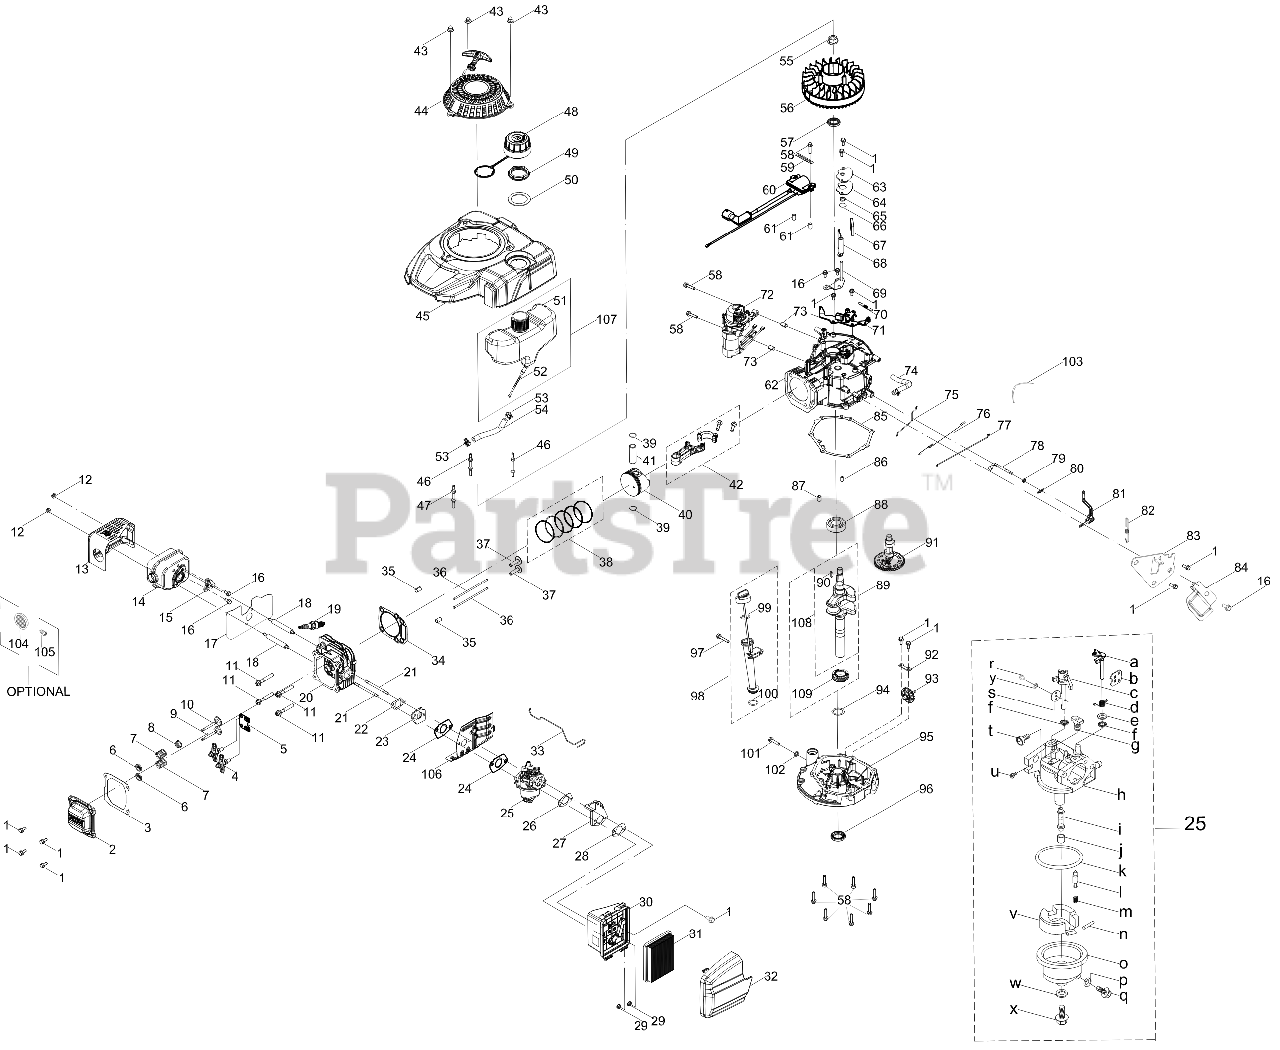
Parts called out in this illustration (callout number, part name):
1	BOLT M6-1 x 14 GR8.8
2	VALVE COVER
3	VALVE COVER GASKET
4	ROCKER ARM ASSEMBLY
5	PUSH ROD GUIDE
6	INTAKE VALVE SPRING RETAINER
7	VALVE SPRING
8	INTAKE VALVE SEAL
9	EXHAUST VALVE
10	INTAKE VALVE
11	SCREW M8 x 54 GR10
12	HEX NUT
13	MUFFLER SHIELD
14	MUFFLER ASSEMBLY
15	THERMOSTAT
16	BOLT M6-1 x 12 GR8.8
17	MUFFLER GASKET
18	STUD M6-1 x 95
19	SPARK PLUG
20	CYLINDER HEAD
21	STUD M6 x 90
22	CARBURETOR GASKET
23	CARBURETOR INSULATOR
24	CARBURETOR GASKET
25	CARBURETOR ASSEMBLY HY-5X70A
26	AIR FILTER BRACKET GASKET
27	AIR FILTER BRACKET
28	AIR FILTER BASE GASKET
29	HEX NUT
30	AIR FILTER HOUSING BASE
31	AIR FILTER
31	Cub Cadet AIR FILTER
31	Genuine Factory Parts AIR FILTER
32	AIR FILTER COVER
33	TEMPERATURE CONTROL LINKAGE
34	CYLINDER HEAD GASKET
35	DOWEL PIN
36	PUSH ROD
37	TAPPET
38	PISTON RING 4PC SET
39	PISTON PIN SNAP RING
40	PISTON ASSEMBLY
41	PISTON PIN
42	CONNECTING ROD ASSEMBLY
43	ACORN NUT
44	RECOIL STARTER ASSEMBLY
45	ENGINE SHROUD W/O IGNITION SWITCH
46	STARTER/SHROUD REAR STUD
47	STARTER SHROUD FRONT STUD M6X74
48	FUEL CAP W/TETHER
49	FUEL TANK NUT
50	FUEL TANK UPPER GROMMET
51	FUEL TANK
52	FUEL FILTER
52	Genuine Factory Parts FUEL FILTER
53	HOSE CLAMP
54	FUEL HOSE
55	FLYWHEEL NUT
56	FLYWHEEL ASSEMBLY
57	CRANKSHAFT SEAL
58	BOLT-M6-1 x 28 GR8.8
59	FLEXIBLE CLAMP
60	IGNITION COIL ASSEMBLY
61	IGNITION COIL SPACER
62	CRANKCASE
63	BREATHER COVER PLATE
64	BREATHER GASKET
65	BREATHER VALVE SPRING
66	BREATHER VALVE
67	BREATHER SCREEN
68	AIR VANE
69	AIR VANE BRACKET
70	ENGINE BRAKE SPRING
71	ENGINE BRAKE ASSEMBLY
72	ELECTRIC STARTER ASSEMBLY
73	DOWEL PIN
74	BREATHER HOSE ASSEMBLY
75	CHOKE LINKAGE
76	THROTTLE SPRING
77	THROTTLE LINKAGE
78	GOVERNOR ARM SHAFT
79	GOVERNOR SEAL
80	COTTER PIN
81	GOVERNOR ARM ASSEMBLY
82	GOVERNOR SPRING
83	COMPONENT BRACKET
84	GOVERNOR SHIELD
85	CRANKCASE COVER GASKET
86	DOWEL PIN
87	DOWEL PIN
88	BEARING
89	CRANKSHAFT
90	FLYWHEEL KEY
91	CAMSHAFT
92	GOVERNOR GEAR MOUNTING PLATE
93	GOVERNOR GEAR/SHAFT ASSEMBLY
94	THRUST WASHER
95	CRANKCASE COVER
96	LOWER CRANKSHAFT OIL SEAL
97	BOLT M6-1 x 35 GR8.8
98	OIL DIPSTICK ASSEMBLY
99	O-RING
100	O-RING
101	OIL DRAIN PLUG
102	WASHER
103	CABLE TIE - 3 x 150
104	SPARK ARRESTOR
105	SCREW M3.5 x 9.5
106	HEAT SHIELD
107	FUEL TANK ASSEMBLY
108	CRANKSHAFT
109	DRIVE TIMING GEAR
